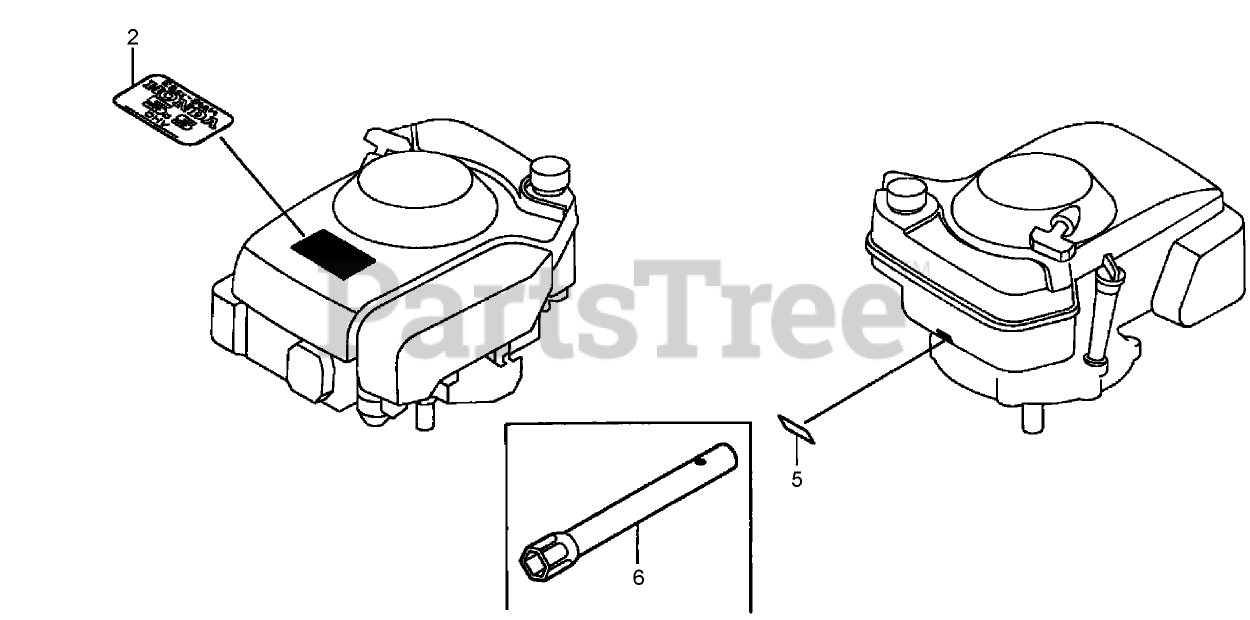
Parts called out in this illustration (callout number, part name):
2	EMBLEM (5.5)
5	MARK-TYPE (A1T)
6	Wrench-Box (P21)
